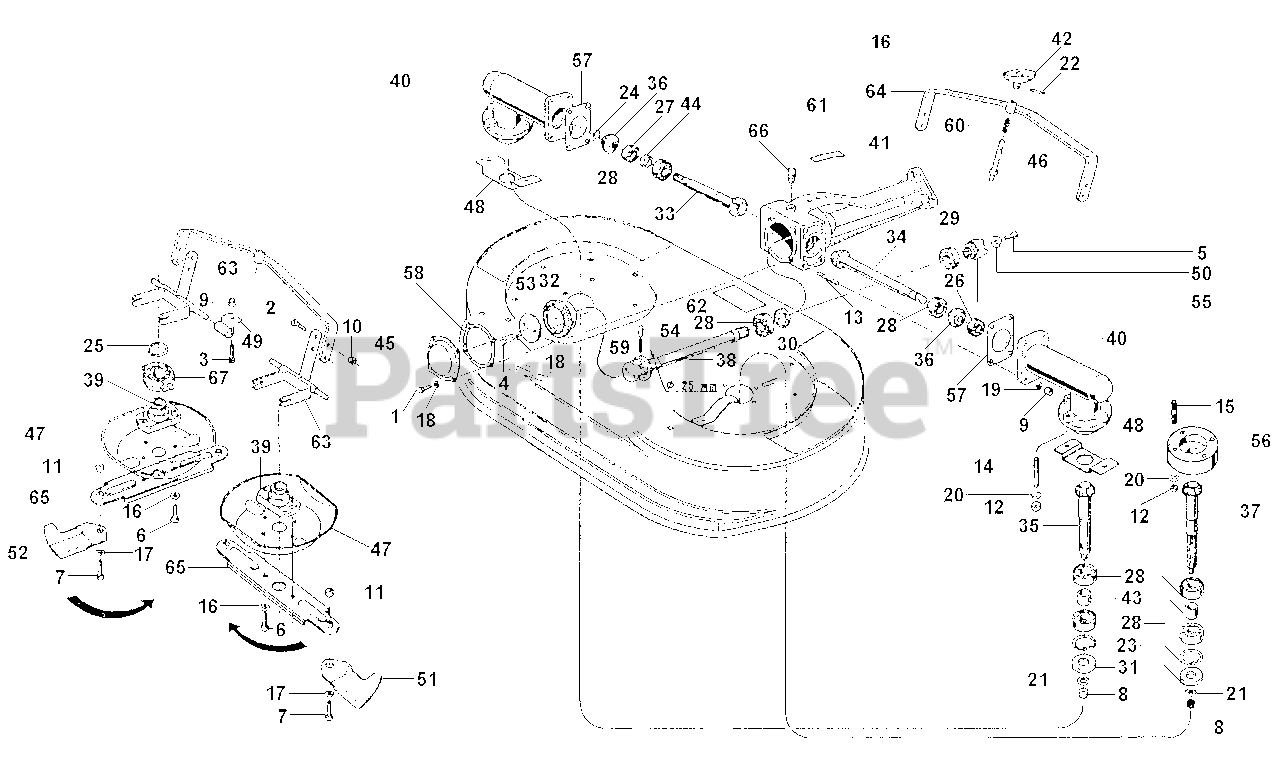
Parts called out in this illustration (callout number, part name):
1	SCREW TE M6X14
2	SCREW TE M8X12
3	SCREW M8X16
4	SCREW M6X12
5	SCREW TE M6X16
6	SCREW M8X14
7	SCREW M10X30
8	NUT, LOW M12
9	NUT, SELF LOCKING M8
11	NUT, SELF LOCKING M10
12	NUT, SELF LOCKING M10 LOW
13	STUD M8X40X14X14
14	STUD M10X37X19X15
15	STUD M10X68X34X15
16	SUPER WASHER 8 DIN 6796
17	SUPER WASHER 10 DIN 6796
18	WASHER, LOCK 6.4
19	WASHER, LOCK 8.4
20	WASHER, LOCK 10.5
21	WASHER, LOCK 13
22	LOCKING PIN 4X24 SPIRAL
23	CIRCLIP, INTERN D 52
24	OUTSIDE CIRCLIP
25	EXT. CIRCLIP D 30
26	BEARING 17X40X12 6203
27	BEARING 20X47X14 6204
28	BEARING SKF 25X52X15 6205
29	BRNG 25X47X12 ST 2RS 6005
30	OIL SEAL 25X40X7
31	OIL SEAL 25X52X7
33	RIGHT SHAFT
35	ROLL CASING
37	BEVEL PINION
38	PROPELLER SHAFT
39	BLADE HOLDER HUB
40	SIDE BODY 2-BLADE MOWER
41	LAWN MOWER CENTRAL BODY
43	SPACER 25X30X24
46	SELECTOR PIN
47	PROTECTION DISC
51	LEFT HAND BLADE
52	RIGHT HAND BLADE
53	DISC, GEAR LOCKING
55	PTO COUPLER
56	CRANKCASE SPACER
57	SIDE GASKET
59	STOP LEVER SPRING
60	FERRULE SPRING
61	TRANSFER FOR LAWN MOWER
63	ADJUSTING LEVER
65	BLADE HOLDER
66	BREATHER CAP 1/4 GAS
